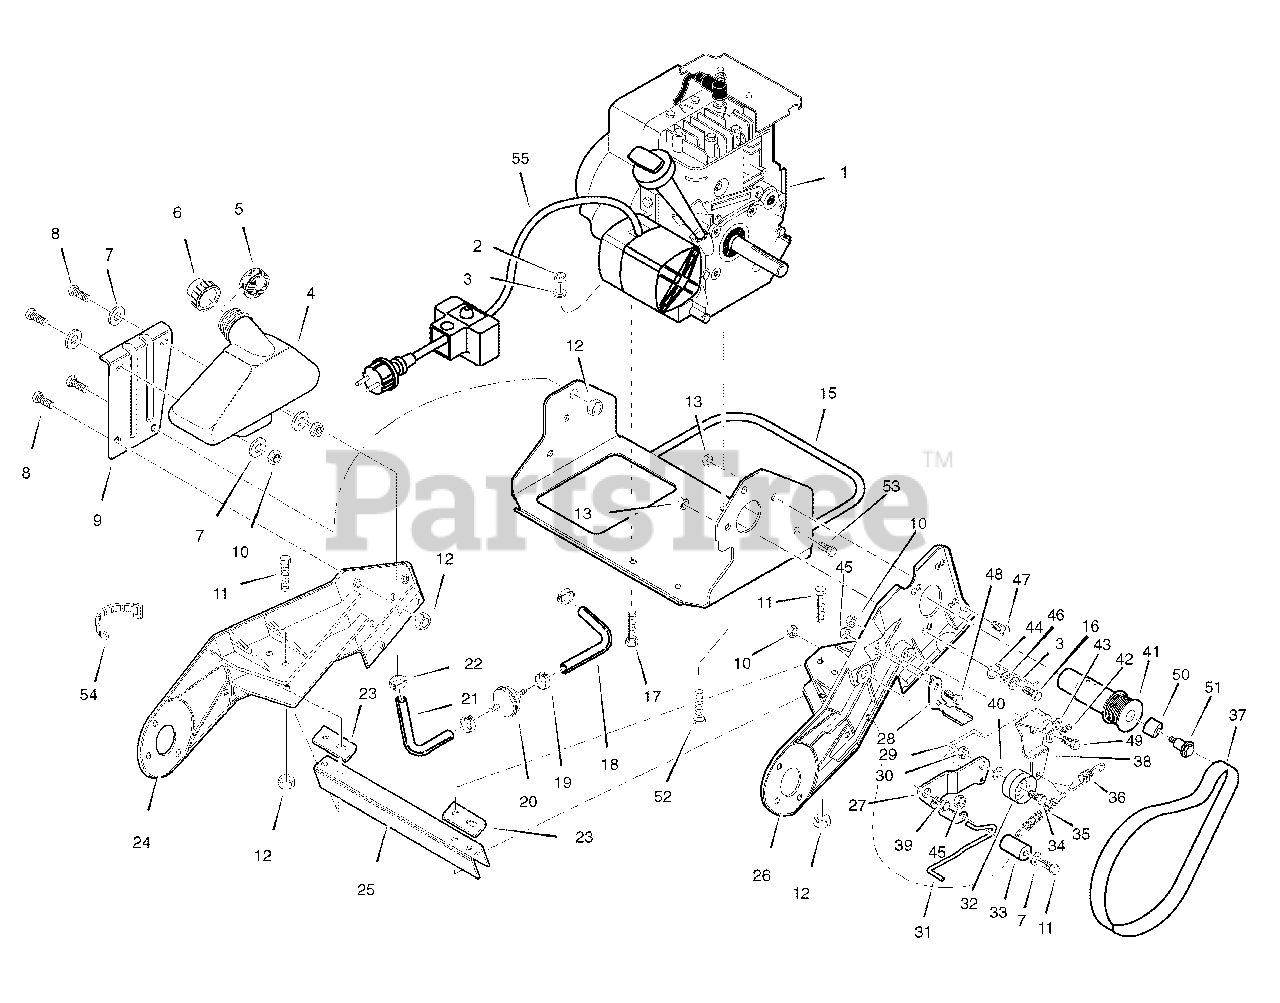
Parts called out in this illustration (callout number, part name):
1	* ENGINE, 5.25TP, Briggs & Stratton
2	NUT, 5/16-18
3	WASHER, Split Lock, 5/16 x 37/64
4	TANK, Fuel 1.5QT
5	RING, Foam, Fuel Tank
6	CAP, Fuel
7	WASHER, Flat, 9/32 x 5/8 OD
8	CAPSCREW, 1/4-20 x 3/4, G5
9	BRACKET, Fuel Tank
10	NUT, Hex, 8-32
11	CAPSCREW, Hex Head, 1/4-20 x 2
12	NUT, Hex, 1/4-20
13	NUT, Hex, Control Lock, 5/16-18
15	CRADLE ASSEMBLY
16	CAPSCREW, Hex Head, 5/16-18 x 3/4
17	CAPSCREW, Engine Mount
18	HOSE, Fuel, 12"
19	CLAMP, Fuel Line
20	FILTER, Fuel
21	HOSE, Fuel, 12"
22	CLAMP, Hose Screw
23	PLATE, Bolting Support
24	FRAME, R.H.
25	CHANNEL, Frame Support
27	BRACKET, Idler Arm
29	ROD, Clutch Linkage
30	NUT, Control Lock, 3/8-16
31	WIRE, Brake
32	PULLEY, Idler
33	ROLLER, Pinch
34	SCREW, 3/8-16 x 1-1/2
35	SPRING, Extension, 3/8 OD x 2-1/2
36	SPRING, Extension, 3/4 OD x 2
37	BELT, Drive, 35-9/64"
38	ARM, Idler Pivot
39	BOLT, Shoulder, 5/16-18 x 1/2
40	WASHER, Flat
41	PULLEY, Engine
42	PIN, Cotter
43	WASHER, Flat #8
44	GUIDE, Belt
45	NUT, 1/4-20
46	WASHER, 11/32 x 11/16 OD
47	SCREW 5/16-18 x 5/8
48	CAPSCREW, Hex Head, 1/4-20 x 5/8
49	CAPSCREW, Hex Head, 8-32 x 3
50	SPACER, Drive Pulley
51	CAPSCREW, Engine Pulley
52	CAPSCREW, Hex Head, 5/16-18 x 7/8
53	SCREW 1/4-20 x 5/8
54	TIE, Cable
55	CORD, Electric, 10FT. 220V
